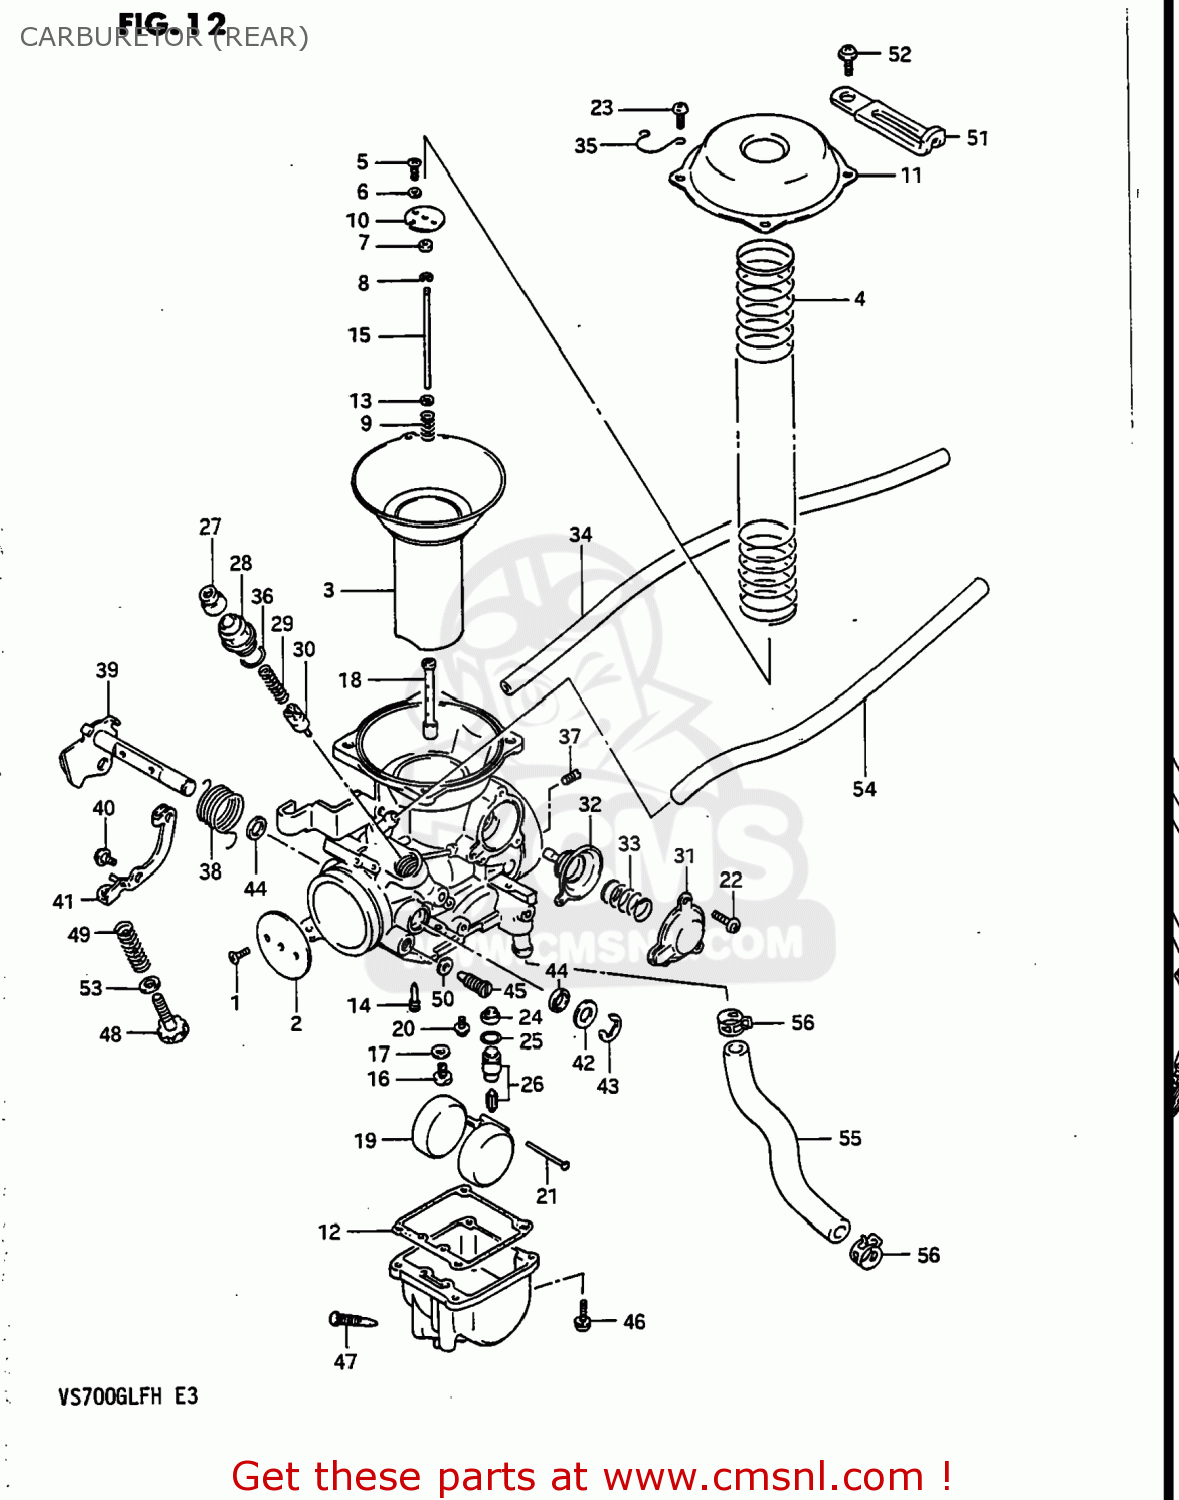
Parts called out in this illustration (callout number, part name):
1	SCREW
2	VALVE,THROTTLE
3	DIAPHRAGM,CARBURETOR
4	SPRING,DIAPHRAGM
5	SCREW
6	LOCK WASHER
7	RING
8	CLIP
9	SPRING
10	PLATE
11	COVER,DIAPHRAGM
12	GASKET,FLOAT CHAMBER (NAS)
13	WASHER
14	JET(40)
15	NEEDLE JET
16	JET,MAIN(132.5)
17	WASHER,NEEDLE NOZZLE
18	JET,NEEDLE
19	FLOAT
20	SCREW
21	PIN,FLOAT
22	SCREWM4X0.7X10
23	SCREW
24	FILTER
25	O-RING,NEEDLE VALVE
26	VALVE ASSY,NEEDLE
27	CAP
28	HOLDER,GUIDE
29	SPRING
30	PLUNGER
31	COVER
32	DIAPHRAGM ASSY
33	SPRING
34	HOSE
35	CLIP
36	O RING
37	JET
38	SPRING
39	SHAFT ASSEMBLY
40	SCREW
41	LEVER,ASSY
42	GASKET,THROTTLE SHAFT (NAS)
43	E RING
44	SEAL,THROTTLE SHAFT
45	SCREW
46	SCREW
47	SCREW,DRAIN
48	ADJUSTER
49	SPRING
50	WASHER
51	CLIP
52	SCREW
53	WASHER
54	HOSE
55	HOSE
56	CLIP
